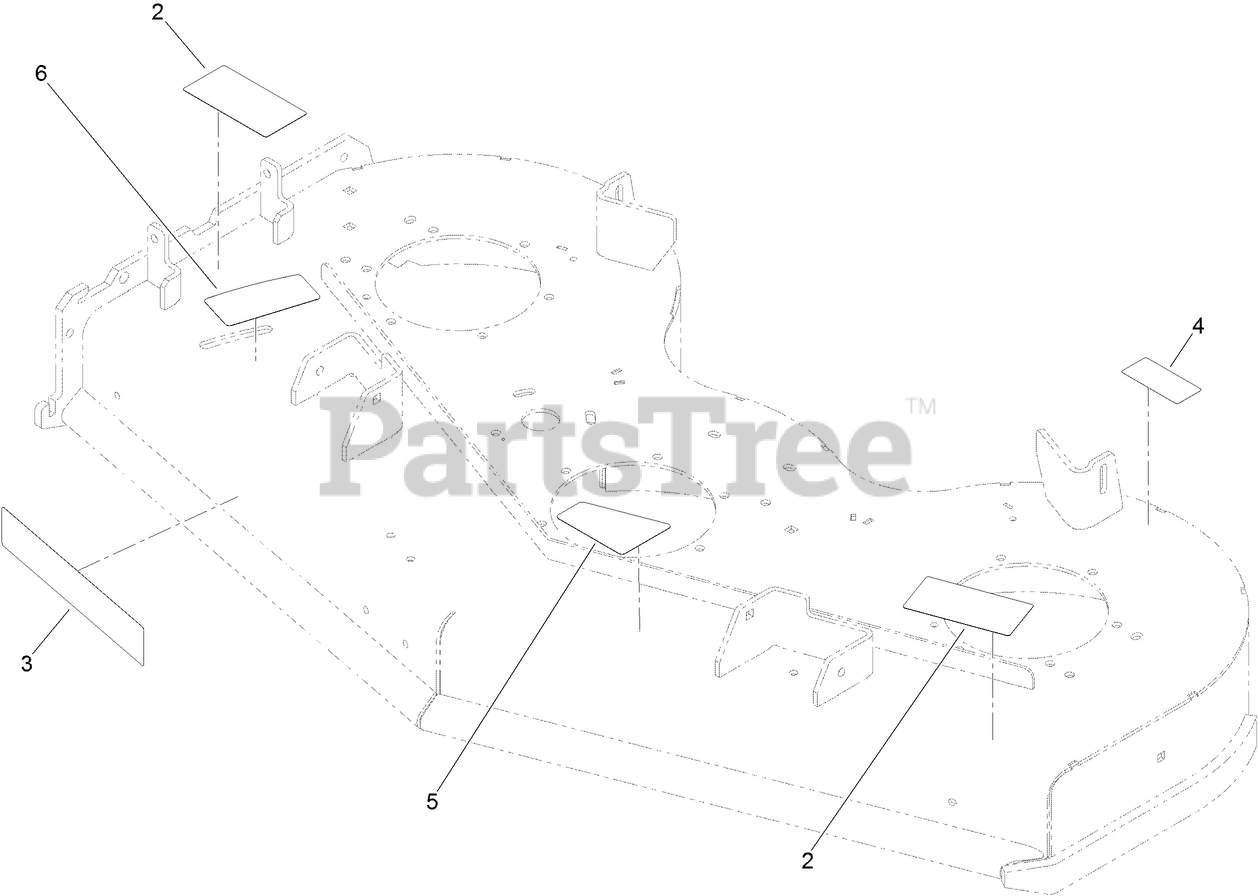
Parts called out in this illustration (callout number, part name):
2	DECAL-DANGER
4	DECAL-BOLT TORQUE
5	DECAL-BELT, TENSION (CE)
6	DECAL-ADJUSTMENT, BAFFLE
